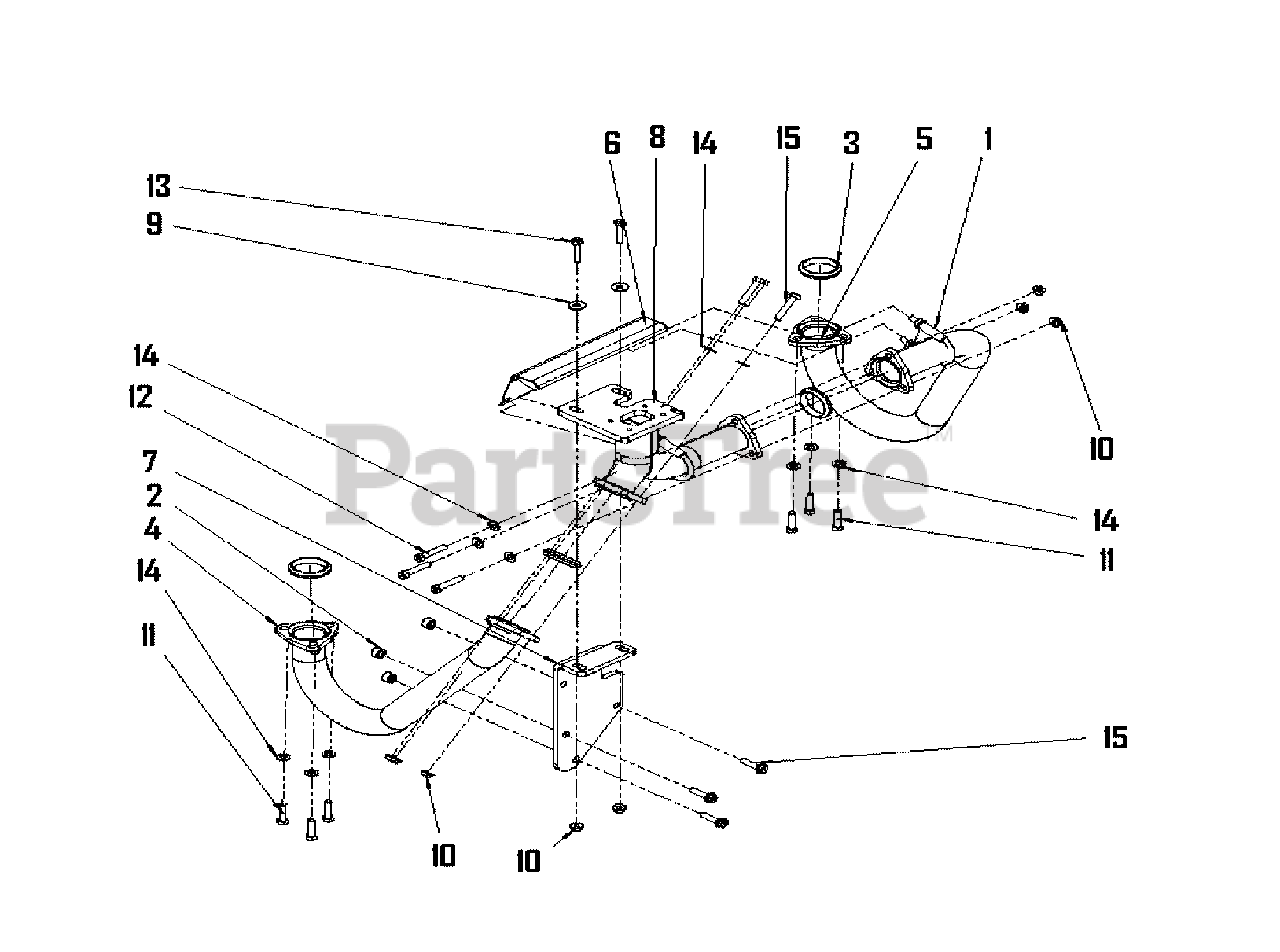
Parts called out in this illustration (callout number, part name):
1	* CLAMP
2	* SPACER
4	* PIPE
5	* PIPE
6	* SHIELD
7	* BRACKET
8	* PIPE
9	* WASHER
10	* NUT
11	* BOLT
12	* BOLT
13	* BOLT
14	* WASHER
15	* BOLT
